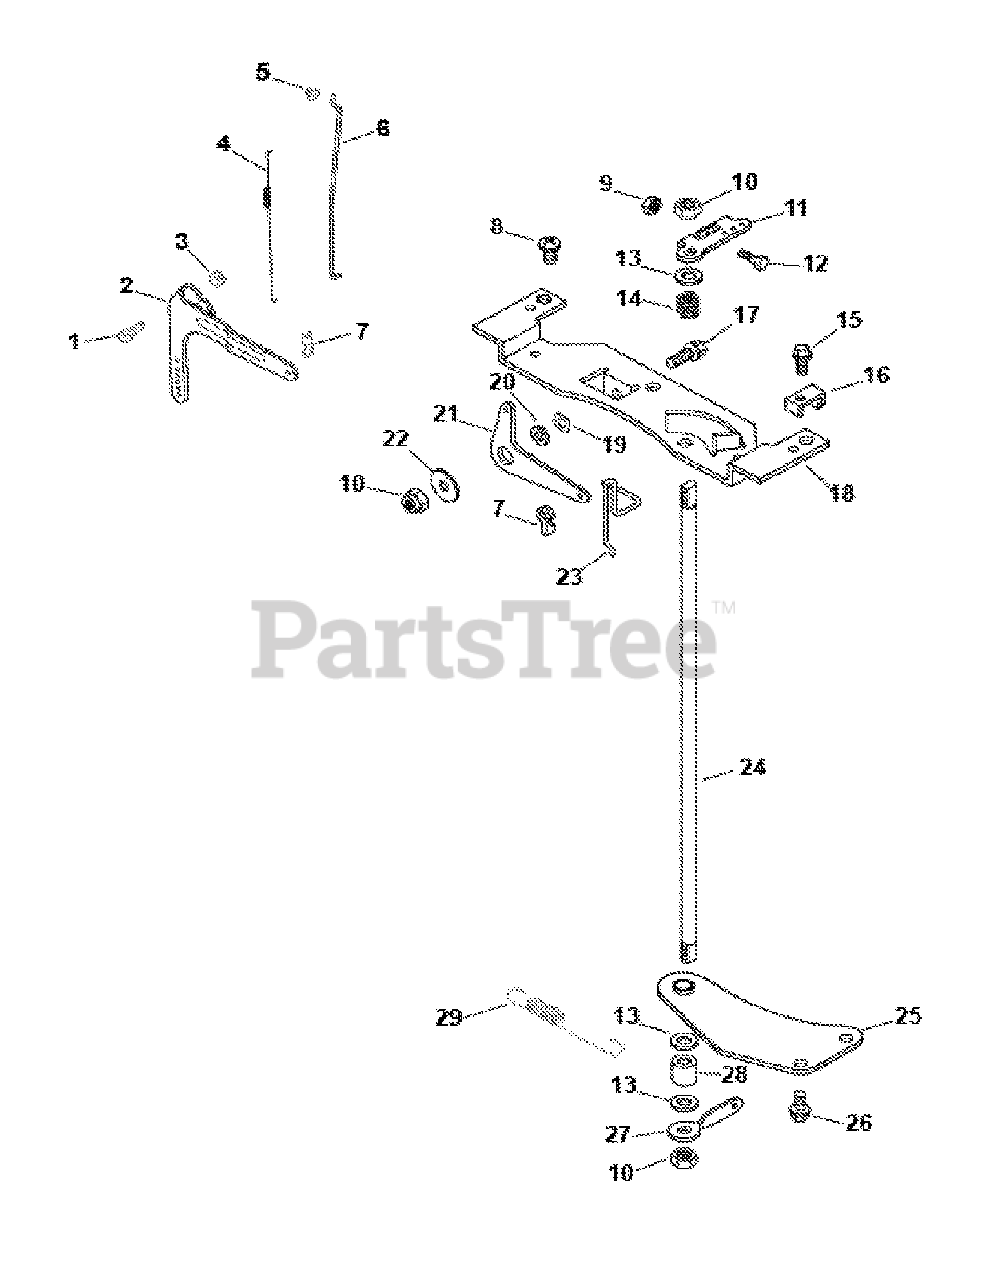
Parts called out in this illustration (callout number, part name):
1	Round Head Sq. Neck Bolt
2	Governor Lever
4	Linkage Spring
5	Linkage Retainig Bushing
6	Throttle Linkage
7	Linkage Retainig Bushing
10	Nut
11	Throttle Control Lever
14	Throttle Shaft Spring
15	Screw
16	Cable Clamp
17	Hex Flange Screw
18	Control Bracket
23	Choke Linkage
24	Throttle Shaft
25	Throttle Shaft Bracket
27	Throttle Control Lever
29	Governor Spring
